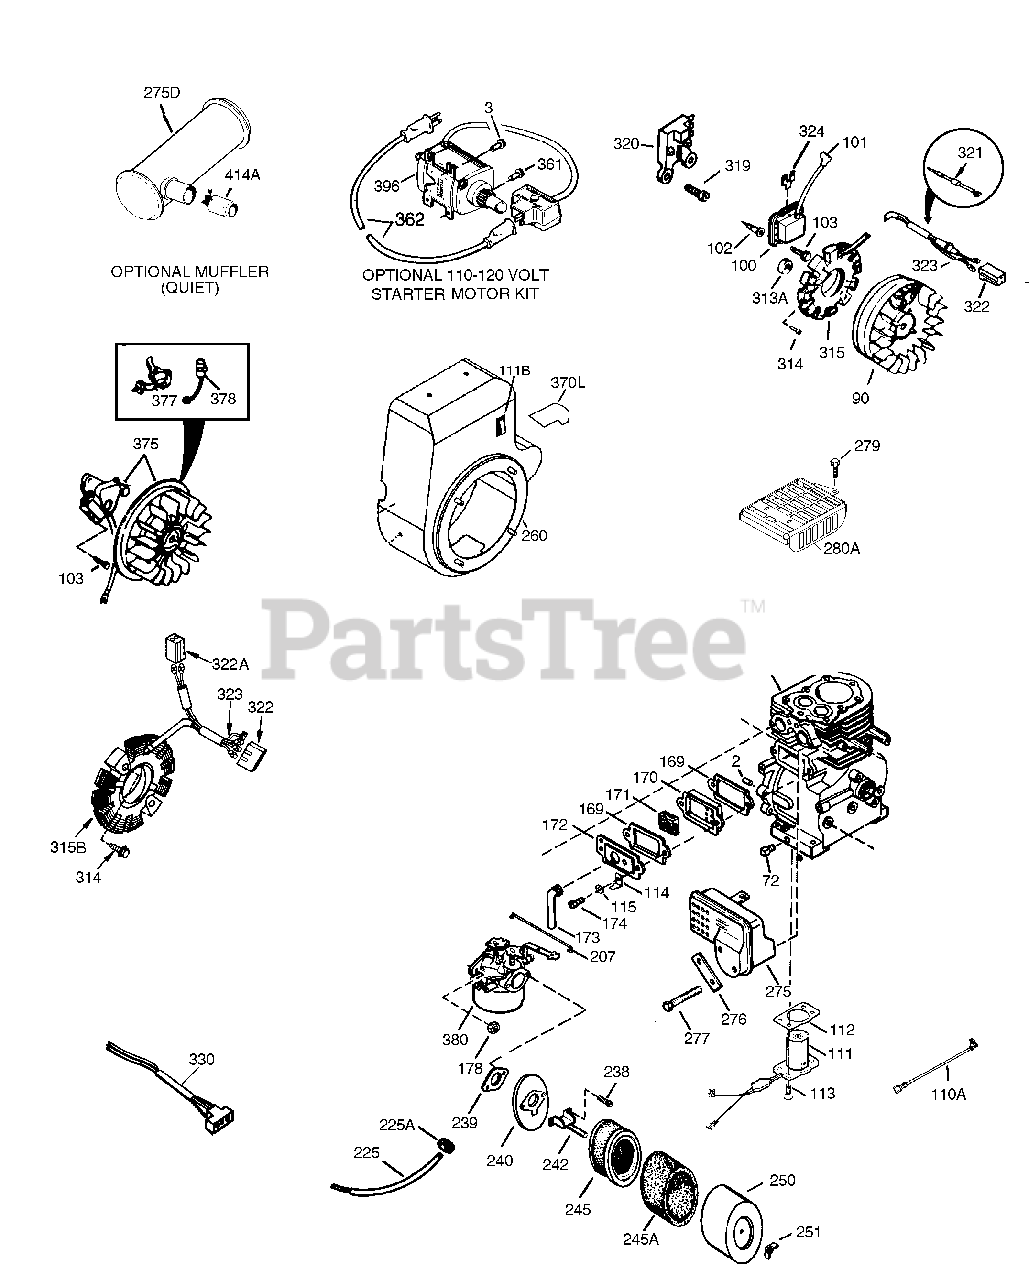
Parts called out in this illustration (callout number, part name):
2	Dowel Pin
3	Screw, 1/4-20 x 1/2"
37A	Lock Nut, 8-32
64	Screw, 1/4-20 x 5/8"
72	Oil Drain Plug (Sq. hd., 1/4-18)
90	Flywheel (w/ring gear) (3 Amp)
100	Solid State Ignition
101	Cover, Spark plug
102	Stud, Solid state mounting
103	Screw, Torx T-15, 10-24 x 1"
129	Screw, 5/16-18 x 1-3/4 Use as requir ed
131	Screw, 1/4-20 x 1/2" Use as required
131	Screw, 1/4-20 x 5/8 (Use as required)
131A	Screw, 5/16-18 x 5/8"
169	* Gasket, Breather
170	Breather Body
171	Breather Element
172	Valve Cover
173	Breather Tube
174	Screw, 10-24 x 1/2"
178	Nut & Lock Washer 1/4-28
207	Link, Governor lever-to-throttle
222A	Pop Rivet (Can be purchased locally)
260	Blower Housing (For electric starter)
275B	Muffler (Incl. 284, 284A & 416) (This spark arrester mufflercan be used on any model.)
276	Plate, Muffler locking
276	Locking Plate
277	Screw, 5/16-18 x 3-3/16" Use as requi red
277	Screw, 5/16-18 x 4-1/4" Use as requir ed
301A	Fuel Cap (Red 1-1/2" ID) (also availa ble in Packaged Part #740005B) (Red Plastic) (Spurt Resistant, Low Profil e) (Use as required) (1.5" I.D.)
301A	Fuel Cap (Red Plastic) (Spurt Resista nt, High Profile) (Use as required) ( 1.5" I.D.)
301A	Fuel Cap (Red)
301A	Fuel Cap (White Plastic)(Standard) (U se as required) (1.5" I.D.)
313A	Gasket, Stator Used only on Std. poi nt ign.
314	Screw, 1/4-20 x 3/4"
315	Alternator Coil (3 Amp, A.C.) Incl. 3 2 2 & 323
322	Connector, Pyramid
323	Terminal, Male
324	Terminal
330	Ground Wire (One male, One open eyele t)
337	Carburetor Cover
338A	Plug, Cover
370D	Decal, Primer
377	Breaker Points (also available in Pac kaged Part #740037B) gn.)
379	Inlet Needle, Seat & Clip Assy.
380	Carburetor (Incl. 184 & 379) (Refer t o Division 5, Section A, page 200 for breakdown or Fiche18B, Grid E-13)
414	Opt.Muffler Screen Mini-Bike applica tion
418	Cover & Tube, Muffler use as require d
419	Screw, 8-18 x 3/8" (use as required)
422	Muffler Optional
1159	Screw, 10-32 x 1/2"
1160	Lockwasher
1160	Screw, 10-32 x 1/2"
1185	Hub & Screen Assy.
